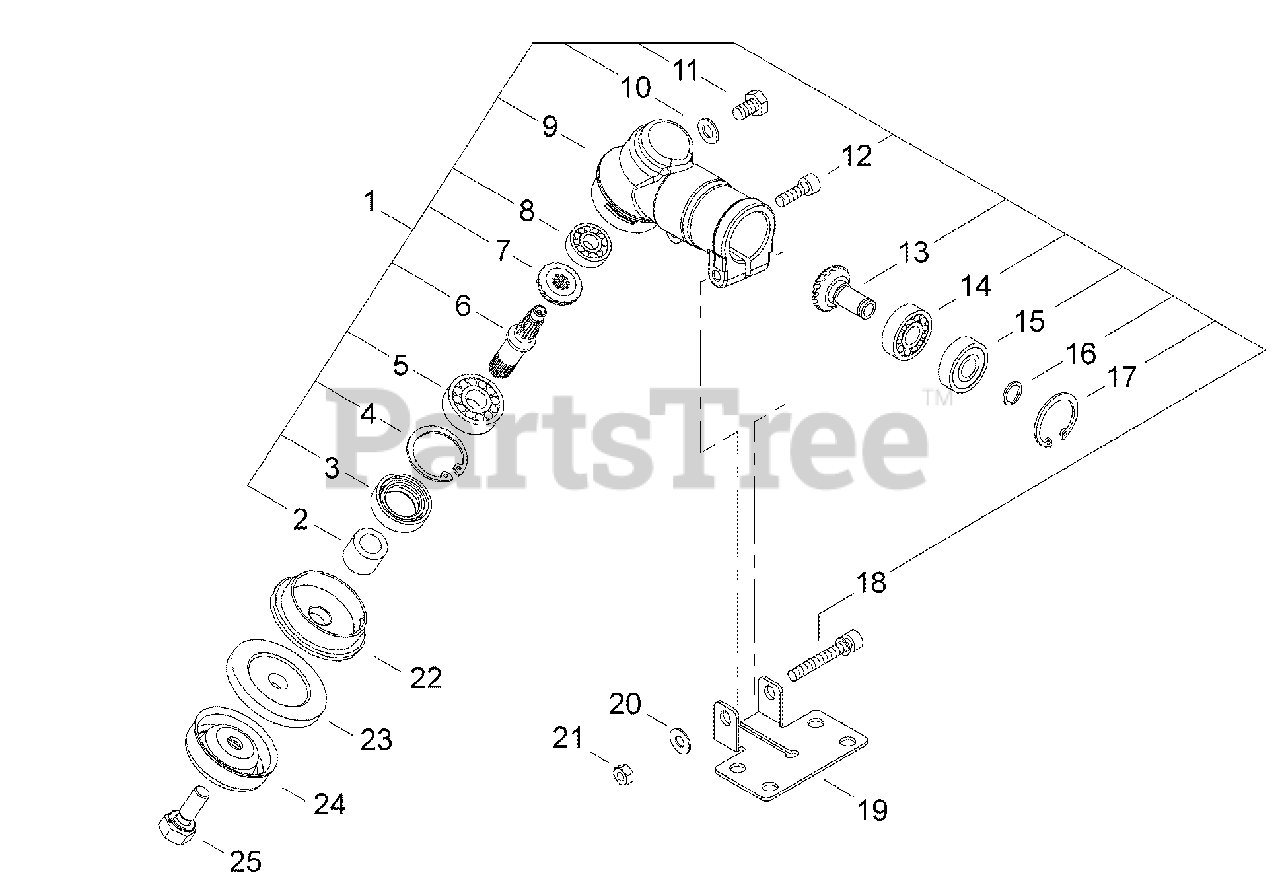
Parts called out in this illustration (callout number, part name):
1	GEAR CASE ASSY
2	SPACER
3	SEAL, OIL
4	RING, SNAP Ø26
5	BEARING, BALL 6000 MOS
6	SHAFT, GEAR
7	GEAR, BEVEL
8	BEARING, BALL 626 MOS
9	HOUSING, GEAR CASE
10	WASHER 6.5×11.5×0.8
11	BOLT M6×10
12	BOLT M5×10
13	GEAR, PINION
14	BEARING, BALL 609 MOS
15	BEARING, BALL 609Z MOS
16	RING, SNAP Ø9
17	RING, SNAP Ø24
18	BOLT M5×40
19	PLATE, SHIELD MOUNTING
20	WASHER 5 MM
21	NUT M5
22	PLATE, ADAPTOR - UPPER
23	PLATE, ADAPTOR - LOWER
24	GUARD, BOLT
25	BOLT M7×20
